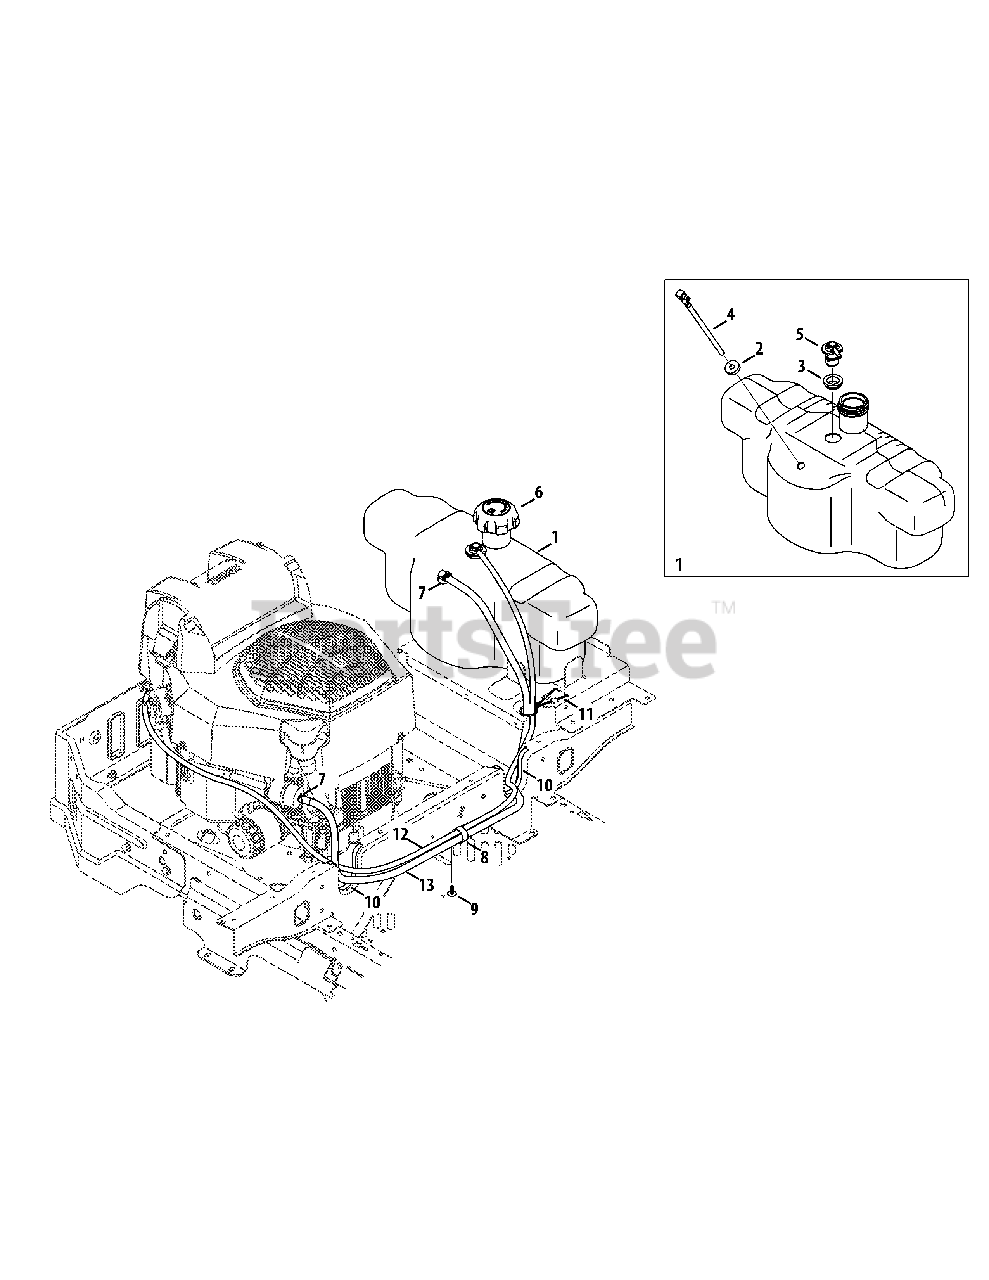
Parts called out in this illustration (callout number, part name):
1	Fuel Tank
2	Fuel Tank Bushing
3	Rubber Grommet
4	Fuel Pickup Fitting
5	Rollover Valve
6	Fuel Cap
7	Hose Clamp, .490 Dia.
8	Hose Clamp, 1.0
9	Ratchet Clip, .250
10	Trim Strip
11	Tank Support Rod
12	Fuel Hose, Low Permeation, 1/4
13	Vent Hose
